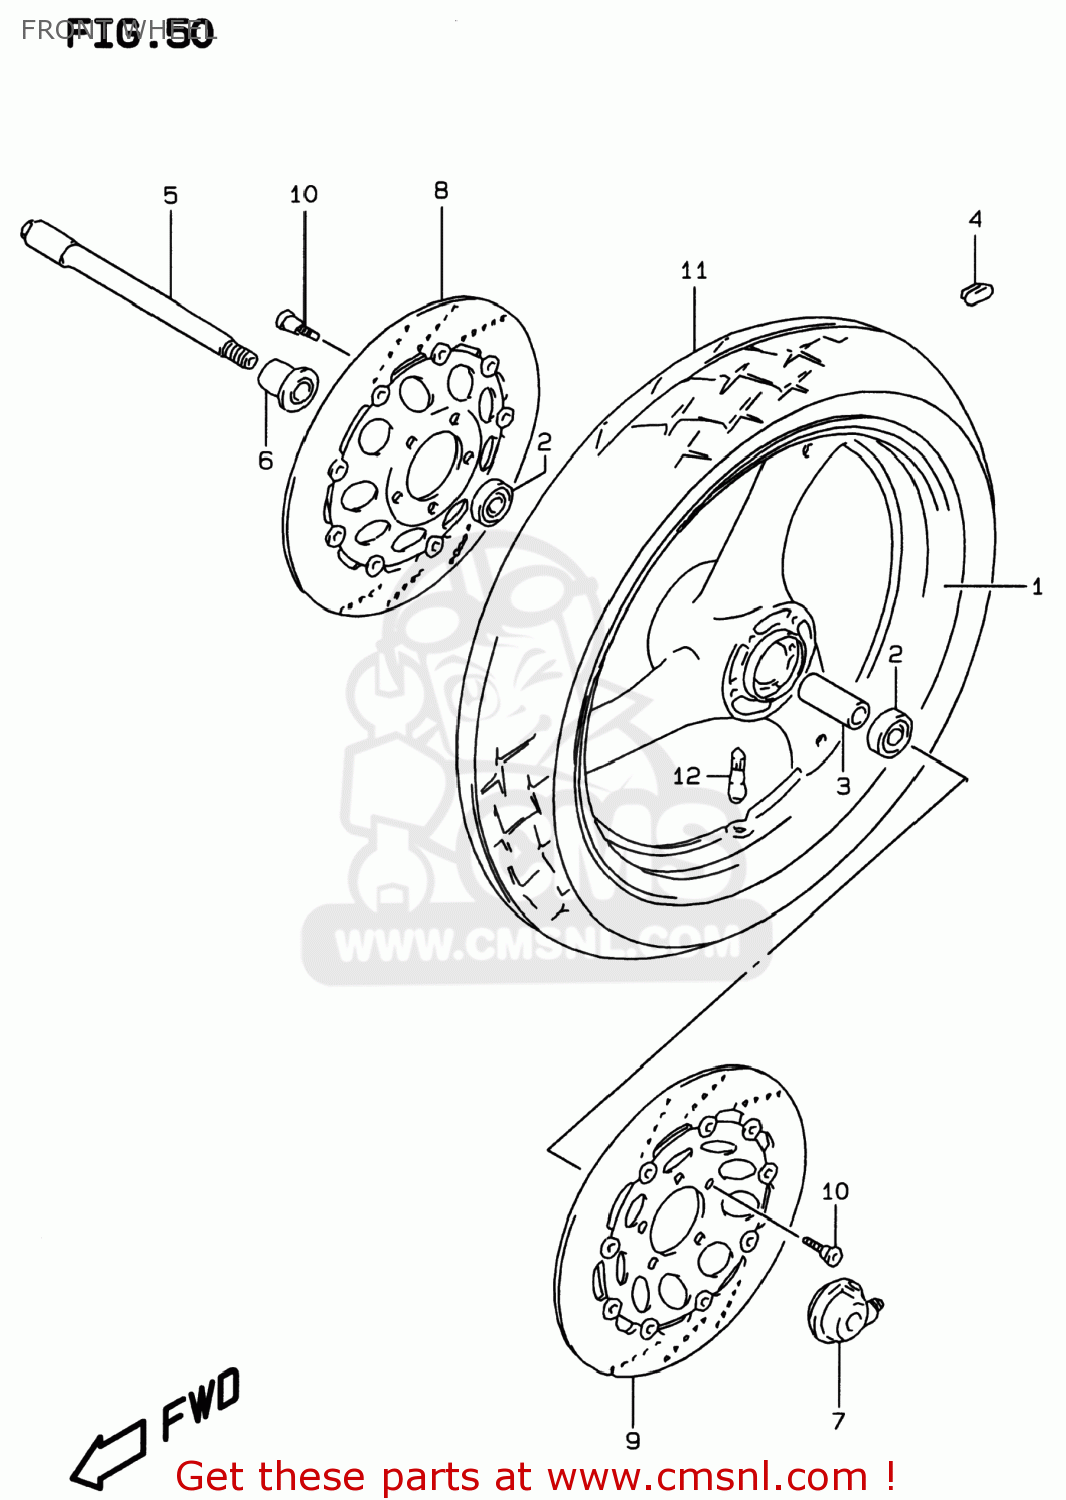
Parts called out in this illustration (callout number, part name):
1	WHEEL,FRONT (17XMT3.00)(
2	BEARING
3	SPACER(17.5X22.5X73)
4	BALANCER,WHEEL (10G)
5	AXLE,FR
6	SPACER,FR AXLE,R
7	BOX ASSY,SPEEDOMETER GEAR
8	DISC,FR BRAKE,R
9	DISC,FR BRAKE,L
10	BOLT 8X33
11	TIRE,FRONT 110/70-17.5
12	VALVE ASSY,WHEEL RIM(TR412)
